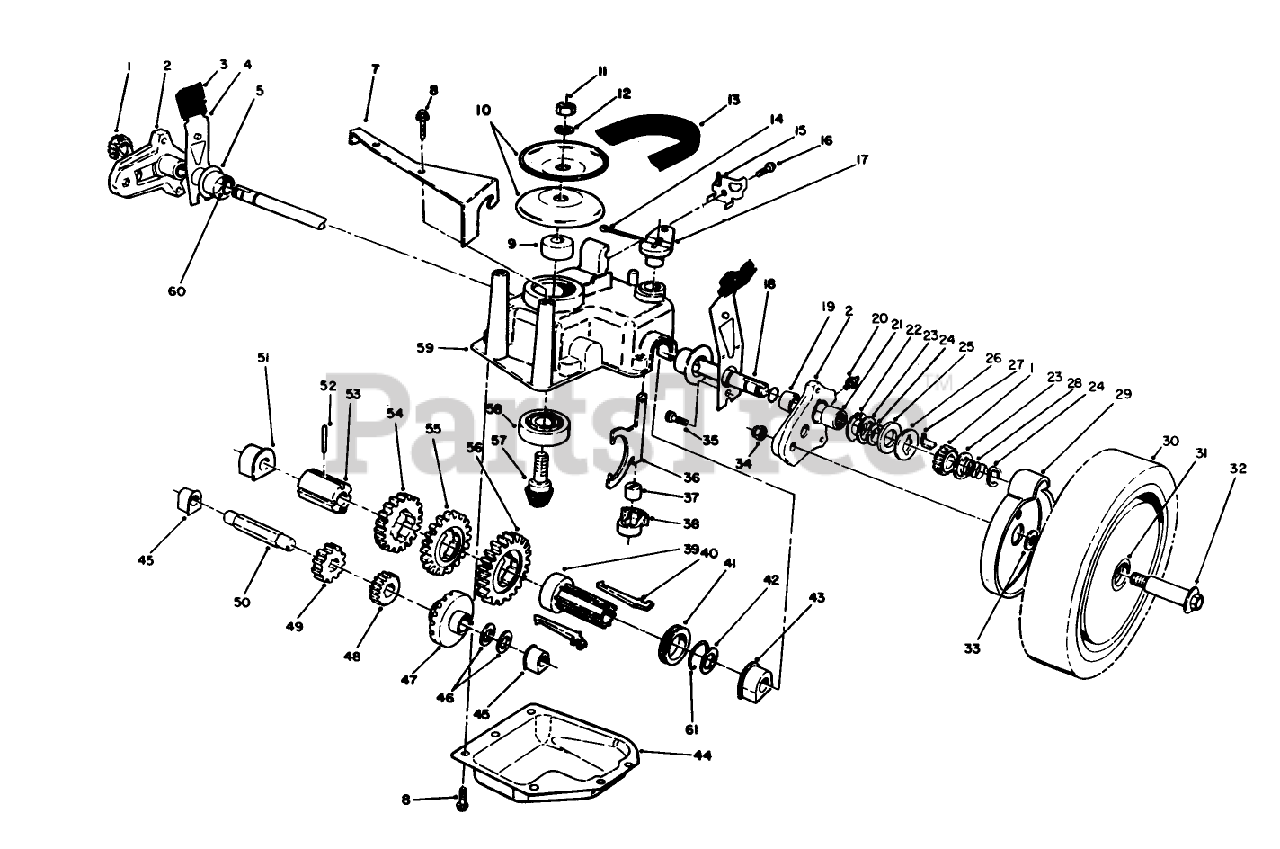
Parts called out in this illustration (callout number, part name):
1	GEAR-PINION
2	PIVOT ARM ASM
3	KNOB-ARM
4	SPRING ARM ASM SP
5	CAP-END
8	SCREW-HWHTF
9	SPACER
11	NUT-HEX
12	WASHER-FLAT
13	V-BELT
14	PIN-COTTER
15	CLAMP-CABLE
16	SCREW-HWHTF
17	LEVER-SHIFT
18	SHAFT-OUTPUT
19	BUSHING
20	FITTING-GREASE
22	WASHER-ARM, PIVOT
23	WASHER-THRUST, KEYED
24	RING-RETAINING,CLIP
25	RING-FRICTION
26	WASHER-CLUTCH
27	KEY-ROCKING, LH
28	SPRING-COMPRESSION
29	COVER-WHEEL
31	BUSHING
32	WHEEL BOLT
33	SPACER-COVER, WHEEL
35	SCREW-HWH
36	YOKE-SHIFT
37	BUSHING-YOKE
38	RETAINER-FORK, SHIFT
39	SLEEVE-KEY, SHIFT
40	KEY-SHIFT
41	COLLAR-SHIFT
42	WASHER-PLAIN
43	BUSHING-OUTPUT
45	BUSHING
46	WASHER-THRUST
48	PINION-20T
49	PINION-25T
51	BUSHING
52	PIN-SPRING
53	SLEEVE-GEAR
54	GEAR-39T
55	GEAR-44T
56	GEAR-49T
58	BEARING-BALL
59	CASE-GEAR, UPPER
60	O-RING
61	CLIP-SPRING
